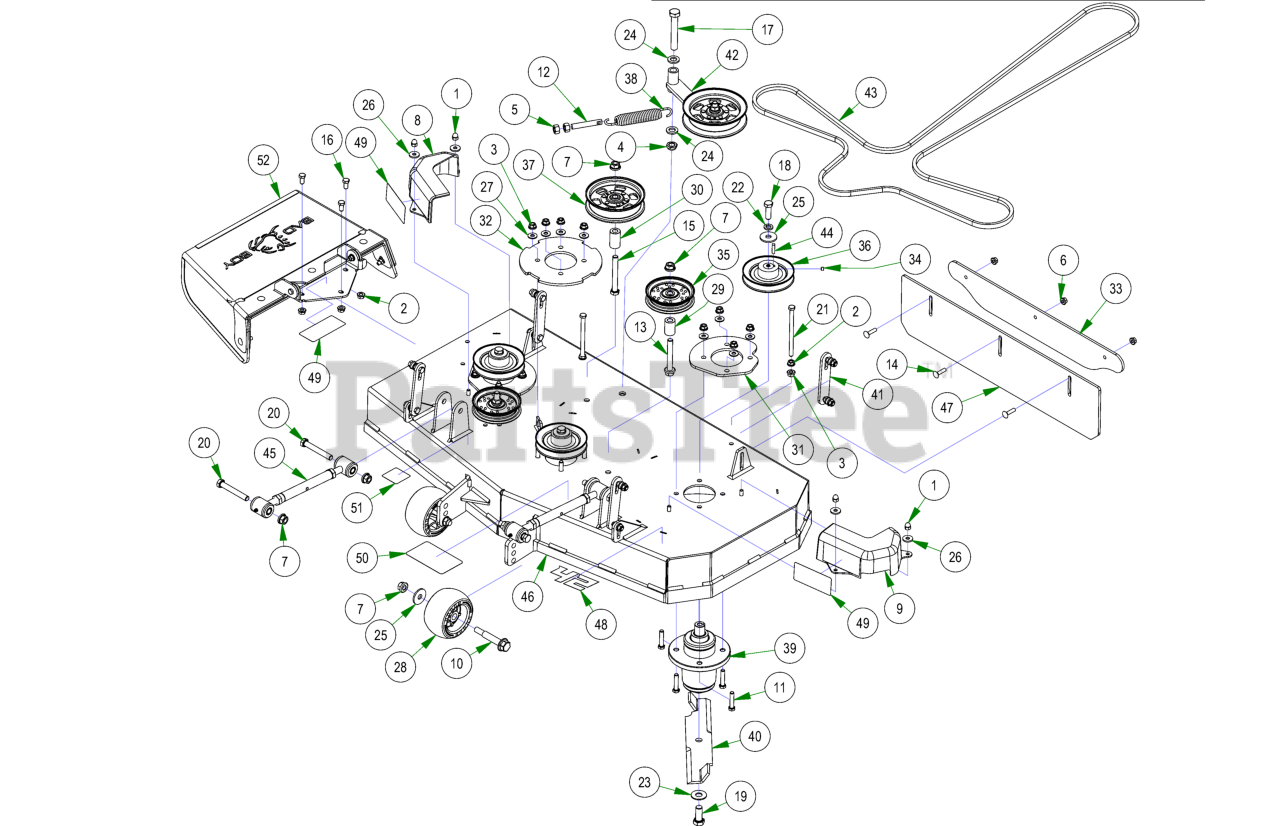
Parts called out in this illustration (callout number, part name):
1	5/16-18 ACORN NUT HIGH-CROWN ZC
2	3/8-16 HEX SERRATED FLANGE NUT HARD/ZINC
3	3/8-16 NYLON INSERT FLANGE LOCKNUT (GR.F) ZINC
4	5/8-11 NYLON INSERT JAM LOCKNUT ZINC
5	1/2-13 HEX NUT ZINC
6	5/16-18 NYLON INSERT FLANGE LOCKNUT ZINC
7	1/2-13 NYLON INSERT FLANGE LOCKNUT ZINC
8	pulley cover chute side
9	pulley cover non-chute side
10	Deck Wheel Bolt
11	3/8-16 X 1-3/4 HEX C/S (GR.5) ZC
12	All Thread
13	1/2-13 X 3-1/2 HEX FLANGE BOLT (GR.8) ZINC
14	5/16-18 X 1-1/4 CARRIAGE BOLT ZINC
15	1/2-13 X 4 HEX CAP SCREW (GR.8) ZINC YELLOW
16	3/8-16 X 3/4 HEX CAP SCREW (GR.5) ZINC
17	5/8-11 X 4 HEX CAP SCREW (GR.8) ZINC YELLOW
18	1/2-20 X 1-1/2 HEX CAP SCREW (GR.5) ZINC
19	5/8-18 X 1-1/2 HEX CAP SCREW (GR.8) ZINC YELLOW
20	1/2-13 X 3-1/2 HEX CAP SCREW (GR.5) ZINC
21	3/8-16 X 5-1/2 HEX CAP SCREW (GR.5) ZINC
22	1/2 SPLIT LOCKWASHER (GR.8) ZINC/YELLOW
23	5/8 USS FLAT WASHER (1-3/4" OD) GR.8 ZINC YELLOW
24	.635 ID X 1.120 OD X .140 THICK FLAT WASHER NYLON
25	1/2 BELLEVILLE WASHER (1-5/8 OD X .140 THK) ZINC
26	.360 ID X .983 OD X .120 THICK FLAT WASHER NYLON BLACK
27	5/16 USS FLAT WASHER (7/8 OD) ZINC
28	Deck Wheel
29	.502 ID X .750 OD X 1.500 Long Spacer
30	1 3/4" Pulley Spacer
31	42&48 Deck Spindle Support Plate
32	Deck Spindle Support Plate
33	2023 4" & 5" Stripping Kit Plate
34	5/16-24 X 1/4 SOCKET SET SCREW (CUP PT) PLAIN
35	4 3/4 Idler Pulley - ABFI-76
36	42 Maverick HD Spindle Pulley
37	5-3/4 Idler Pulley
38	Deck Idler Spring
39	OUTLAW SPINDLE ASSEMBLY
40	42" High Lift Blade-Outlaw
41	Deck Hanger Assembly
42	2017 MZ/ZT Deck Idler Assembly
43	2023 42" Deck Belt
44	1/4 X 1 SQ MACHINERY KEY 1018 STL PLN
45	2018 Maverick Turnbuckle (Top Link)
46	2023 42" x 5" Deck
47	2023 ZT Stripping Kit Rubber
48	42" Deck Decal
49	Danger Decal-Spindle/Discharge
50	Deck Belt Route Decal
51	Deck Impact Patent Decal 9591803
52	ZT Chute Assembly
